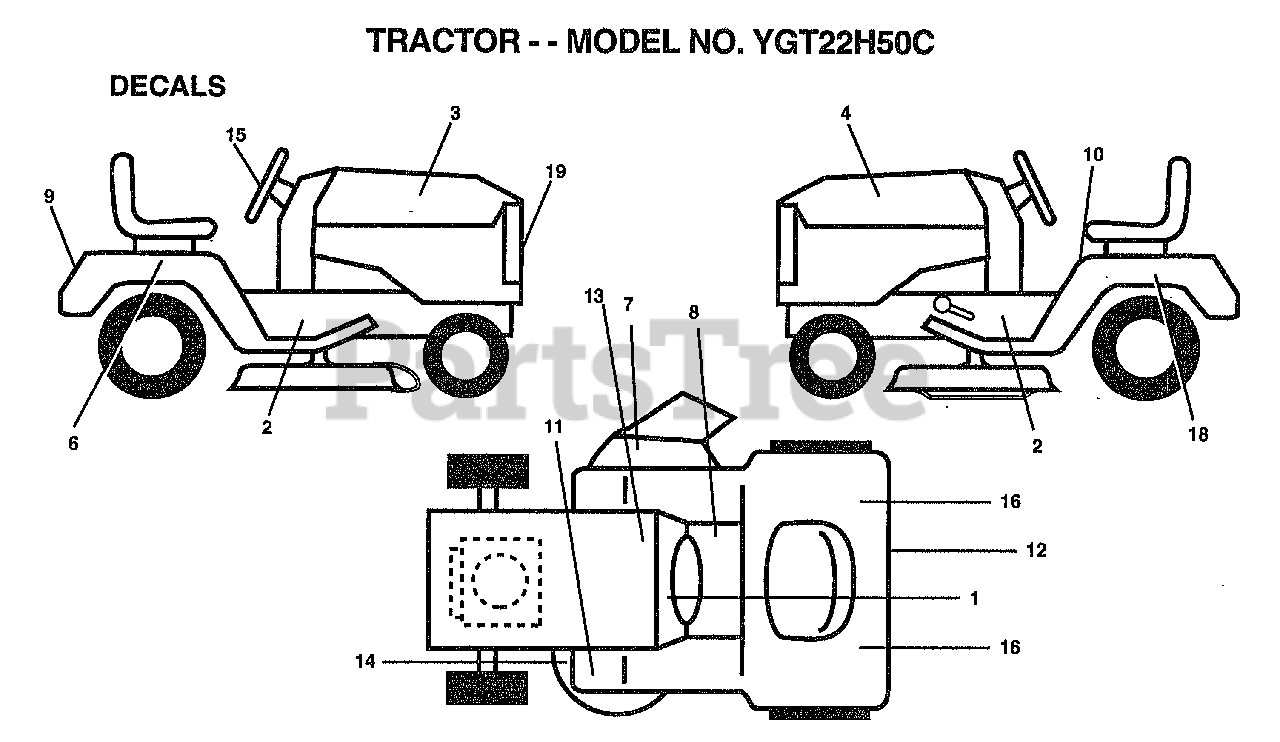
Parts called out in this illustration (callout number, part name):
1	DECAL OPER INSTR.
2	DECAL CHASSIS 50
3	"DECAL HOOD,RH"
4	DECAL HOOD LH
6	DECAL FENDER RH
7	"DECAL, WARNING"
8	DECAL BRAK PARK
9	DECAL FENDER
10	DECAL.CAUT.ENG/FR
11	DECAL T
12	DECAL D-BAR CNTRL
13	DECAL.BATRY.3-3908
15	DECAL INS STRG WH
16	REFLECTOR-TAIL YT
18	DECAL FENDER LH
19	DECAL GRILLE
